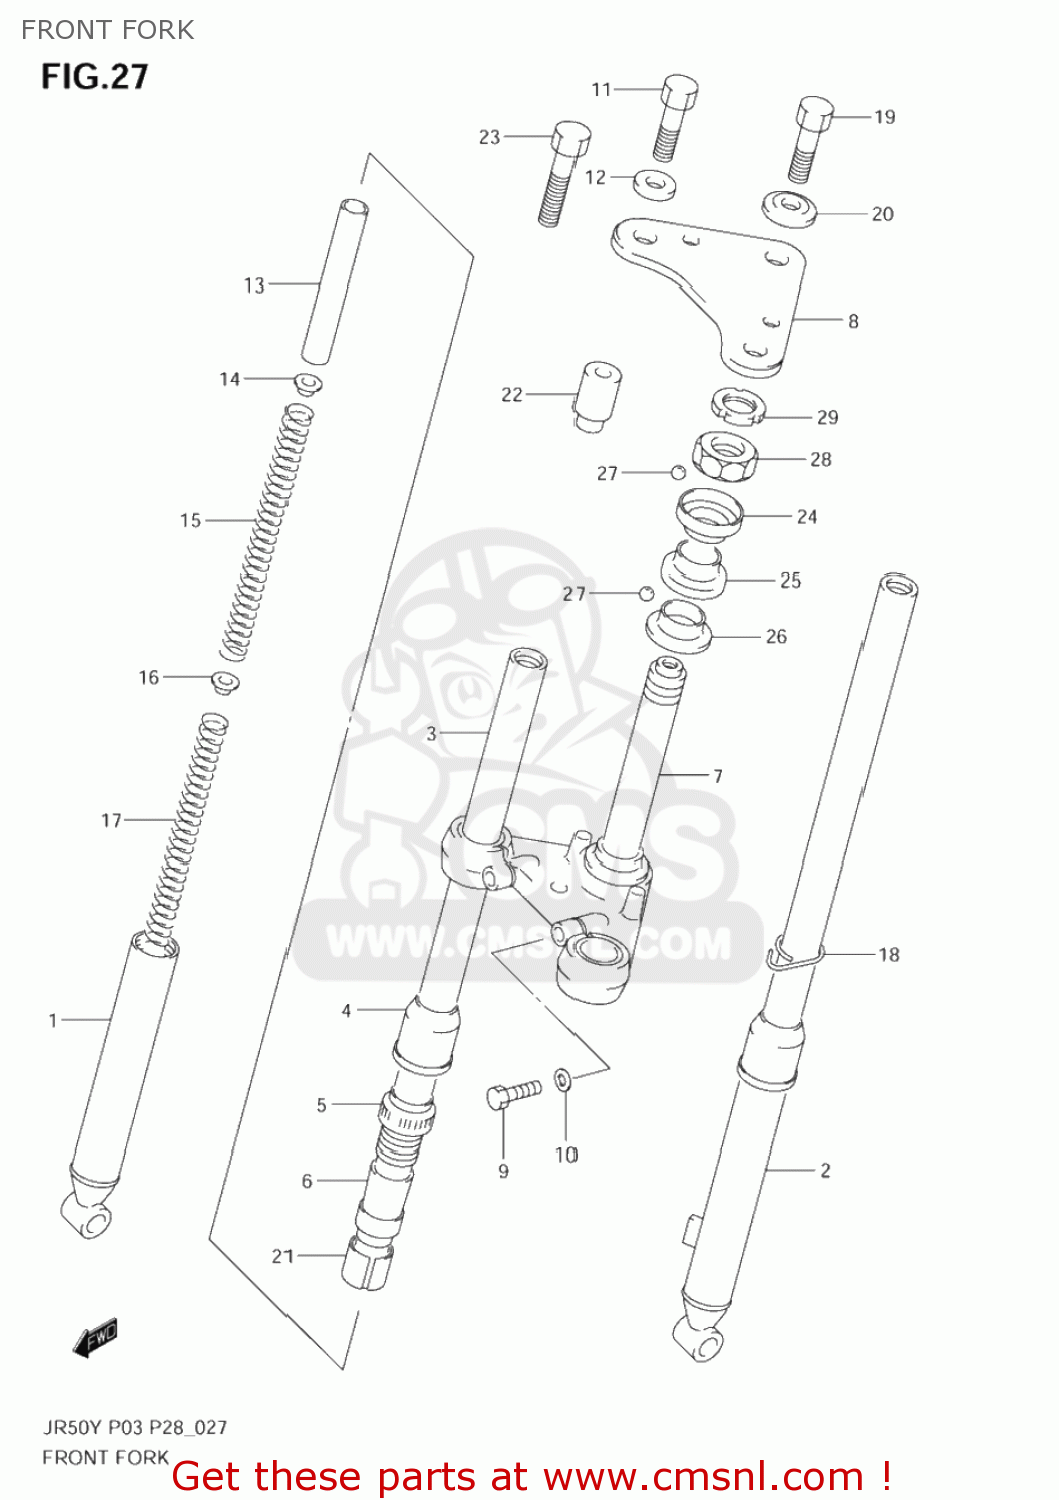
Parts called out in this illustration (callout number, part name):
1	TUBE,OUTER,R
2	TUBE,OUTER,L
3	TUBE,INNER
4	SEAL,DUST
5	NUT,OUTER
6	STOPPER
7	STEM,STEERING
8	HEAD,STEERING STEM
9	BOLT
10	WASHER,LOCK
11	BOLT
12	WASHER,STEERING STEM HEAD
13	SPACER
14	GUIDE,SPRING
15	SPRING,NO.1
16	GUIDE,SPRING NO.2
17	SPRING,NO.2
18	CLIP
19	BOLT
20	WASHER(33.5X10.5X4.2)
21	BUSH,SLIDE(33221-00801)
22	SPACER,FR FORK INNER TUBE
23	BOLT(10X52)
24	RACE,STEERING INNER UPR
25	RACE,STEERING INNER LWR
26	RACE,STEERING,OUTER,LOWER
27	BALL
28	RACE,STEERING,OUTER,UPPER
29	NUT
